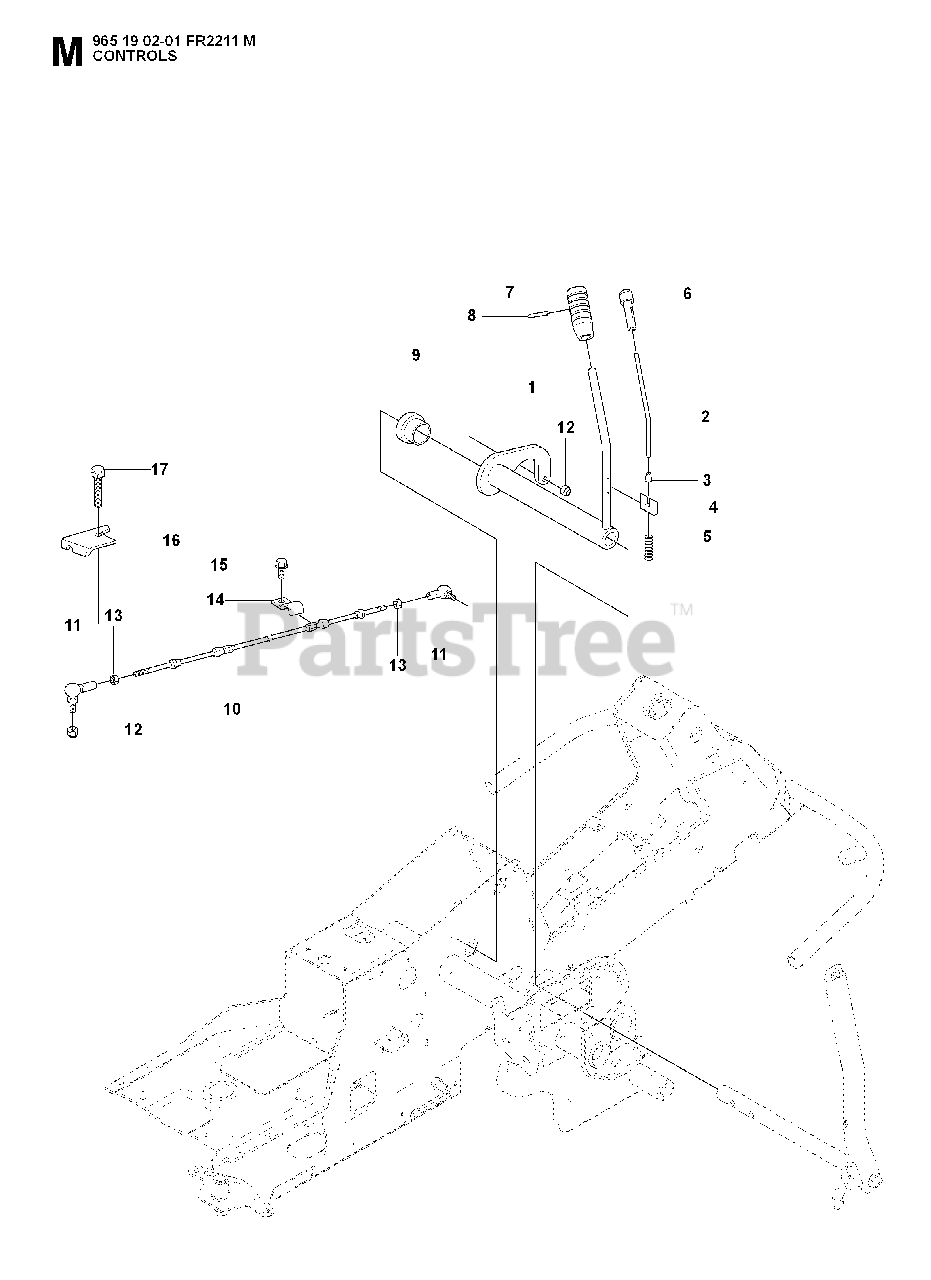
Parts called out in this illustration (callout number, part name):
3	END PIECE
8	SPRING PIN 3X24
9	BUSH
10	%ROD
11	CONNECTOR
12	LOCKNUT M5
